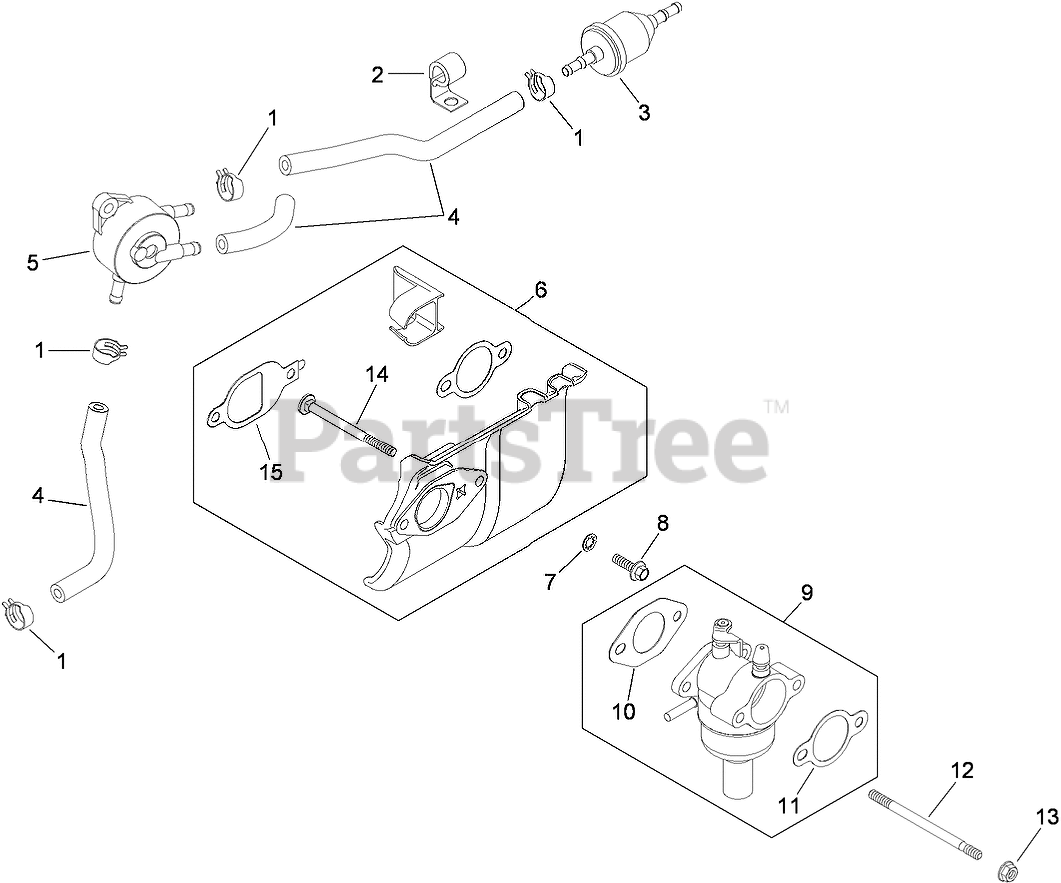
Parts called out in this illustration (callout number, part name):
1	CLAMP-HOSE, SPRING (1/2)
2	CLIP-CABLE
3	FILTER-FUEL
4	LINE-FUEL (24.0 CUT TO LENGTH)
5	PUMP-FUEL
6	HEAT DEFLECTOR ASM (INCLUDES REF 11, 14, 15, 20 332 01-S)
7	Washer-Lock, Internal Tooth (1/4)
8	Screw-Flange, Hex (M6x1.0x20)
9	CARBURETOR (INCLUDES REF 10, 11) (REPAIR KIT/W 12 755 109-S, 12 755 110-S, 12 757 02-S, 12 757 03-S, 12 757 33-S, 12 757 37-S, 20 755 07-S)
10	Gasket-Carburetor
11	Gasket-Base, Air Cleaner
12	Stud-Mounting, Carburetor (M6X1.0X100)
13	NUT-FLANGE (M6X1.0)
14	STUD-CARBURETOR
15	GASKET-DEFLECTOR, HEAT
